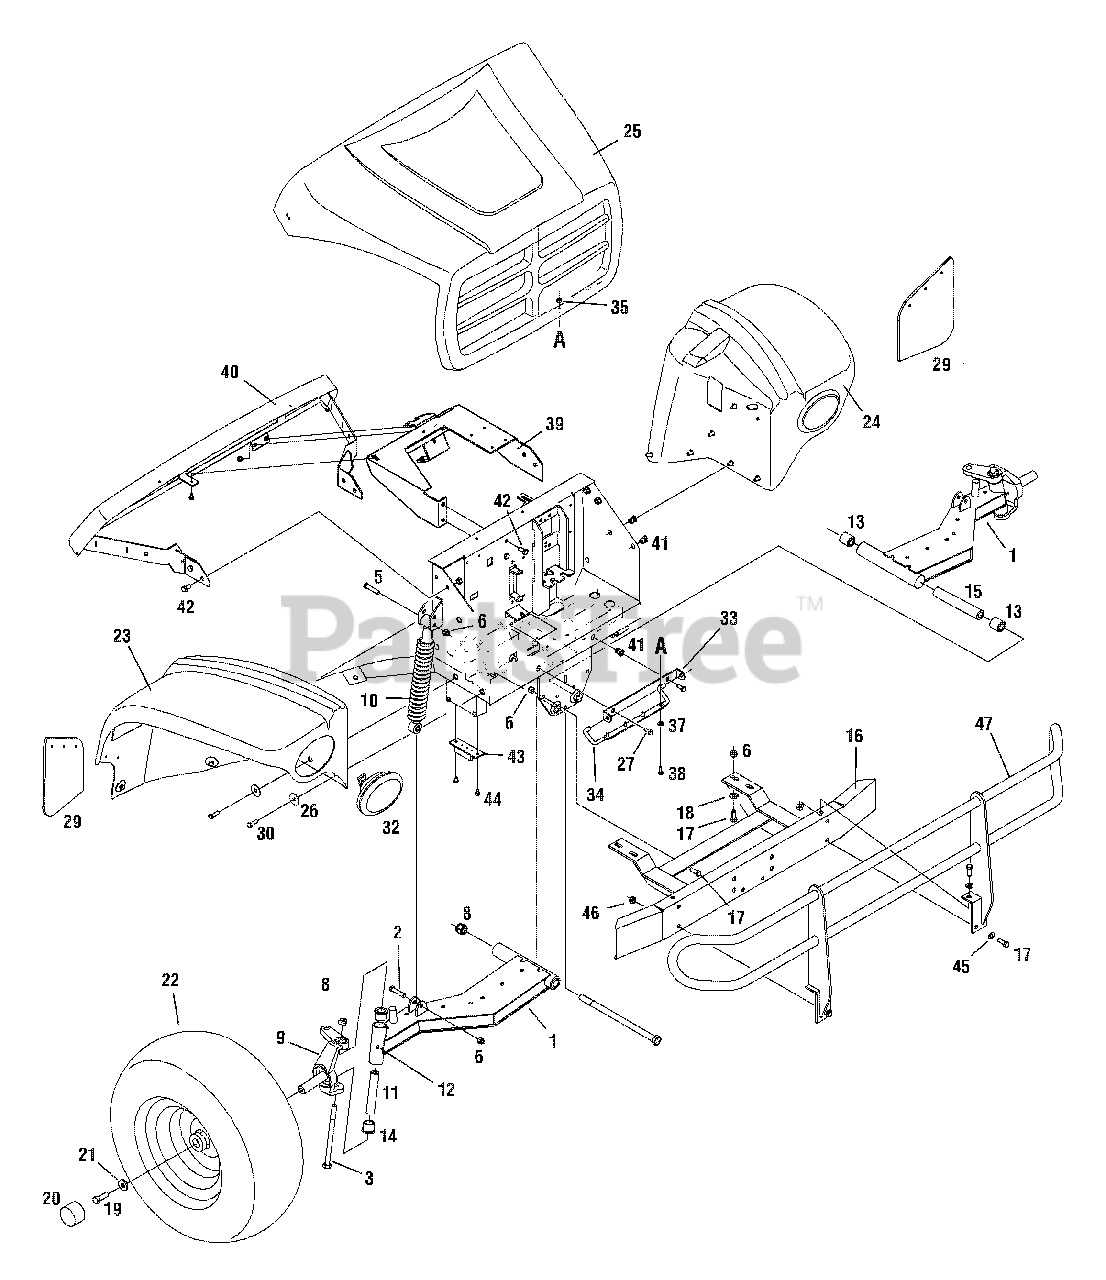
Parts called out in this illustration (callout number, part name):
1	Axle Assembly, Right-front
2	Hex Screw, 3/8-16 x 1.75
3	Hex Screw, 1/2-13 x 7.0, Gr5
4	Hex Screw, 5/8-11 x 11.13, Gr5
5	Hex Screw, 3/8-16 x 2.25
6	Nut, Hex Lock, Nylon, 3/8-16, Gr5
7	Nut, Hex Lock, Nylon, 5/8-11, Gr5
8	Nut, Hex Lock, 1/2-13
9	Steering Control Knuckle, RH
10	Shock Absorber, 2.9 Stroke
11	Tube, .875 x .50 x 4.75
12	Grease Fitting
13	Bearing, .63 ID x 1.19 OD
14	Bushing, Steering
15	Spacer, .645 ID x 1.063 OD
18	Flat Washer, .406 x .875 x .059
19	Hex Screw, 1/2-13 x 1.50, Gr5
21	Flat Washer, .531 x 1.25 x .181
22	RH Wheel Assembly, 22 x 11 x 10
23	Panel Assembly, Right Fender, Camo
24	Panel Assembly, Left Fender, Camo
25	Panel Assembly, Hood, Camo
26	Hex Screw 5/16-18 x 1.00 Gr 5
27	Hex Screw, 5/16-18 x .75
28	Flat Washer, .350 x 1.25 x .06
30	Washer, Bell, .39 x 1.38 x .062
31	Flat Washer, .194 x .62 x .063
32	Headlamp Assembly
35	Nut, Hex Lock, 1/4-20
36	Cotter Pin, Internal, 1.42
37	Washer, Flat, .271 x .63 x .065
38	Hex Screw, 1/4-20 x .75
41	Insert Nut, 5/16-18
42	Hex Screw, 3/8-16 x .75
43	Screw, Self-tapping, 1/4-20 x .5
44	Suspension Bumper
45	Washer, Flat, .406 x .812 x .051
46	Nut, Flange Lock, 3/8-16
47	Brush Guard (order from sales)
